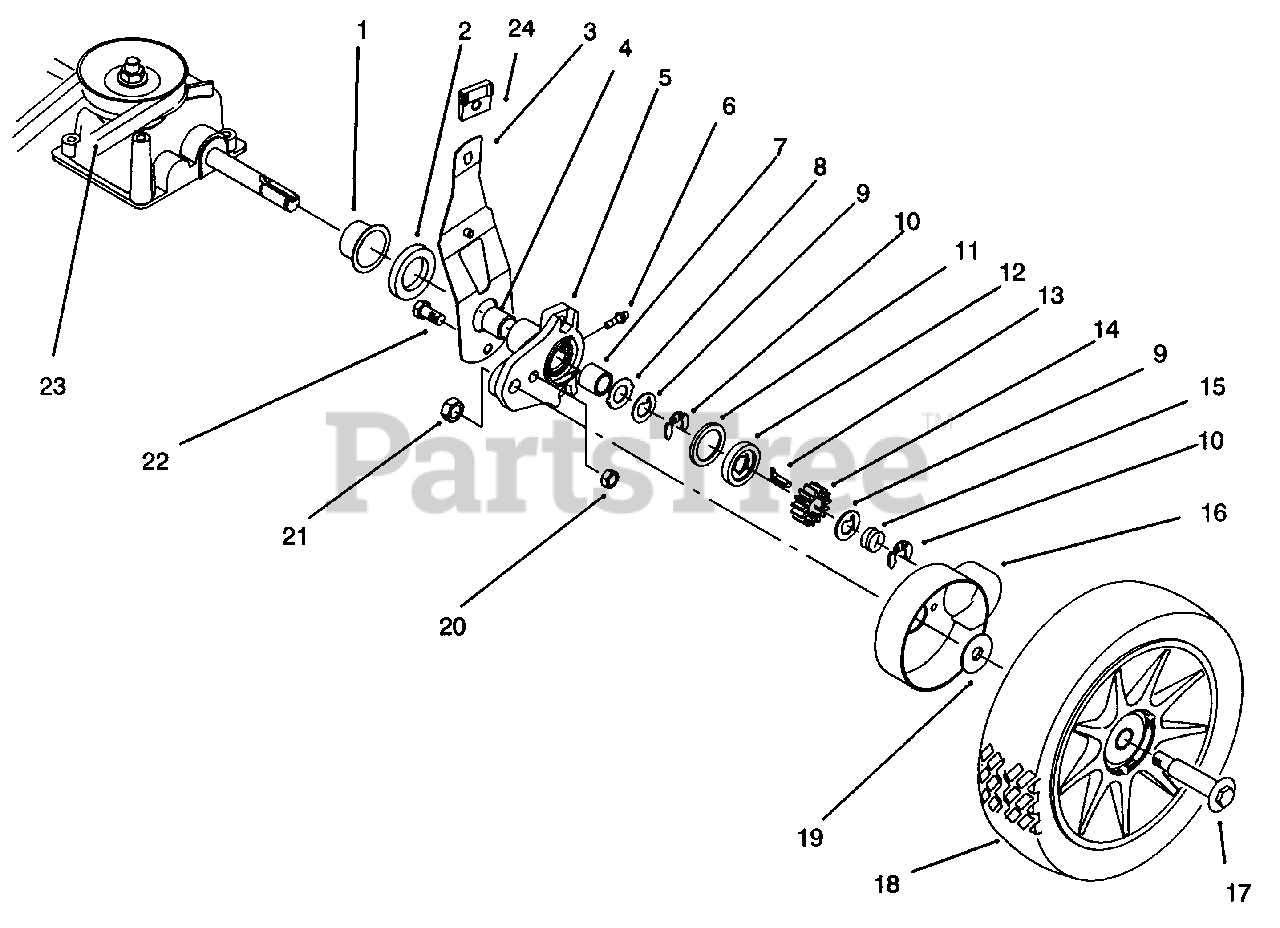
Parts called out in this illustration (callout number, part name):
1	Ring-Isolator
2	Spacer-Axle Shaft
3	Spring Arm Ass'y
5	Pivot Arm Ass'y-Rear
6	Fitting-Grease (Ref.)
8	Washer-Thrust Pivot Arm
9	Washer-Thrust, Keyed
10	Ring-Klip
11	Ring-Friction
12	Washer-Clutch, Plastic
13	Key-Rocking LH
14	Gear-Pinion
15	Spring-Compression
16	Cover Wheel
17	Bolt-Wheel
18	Wheel Ass'y-8"
19	Washer-Stepped
23	"V" Belt
24	Knob
